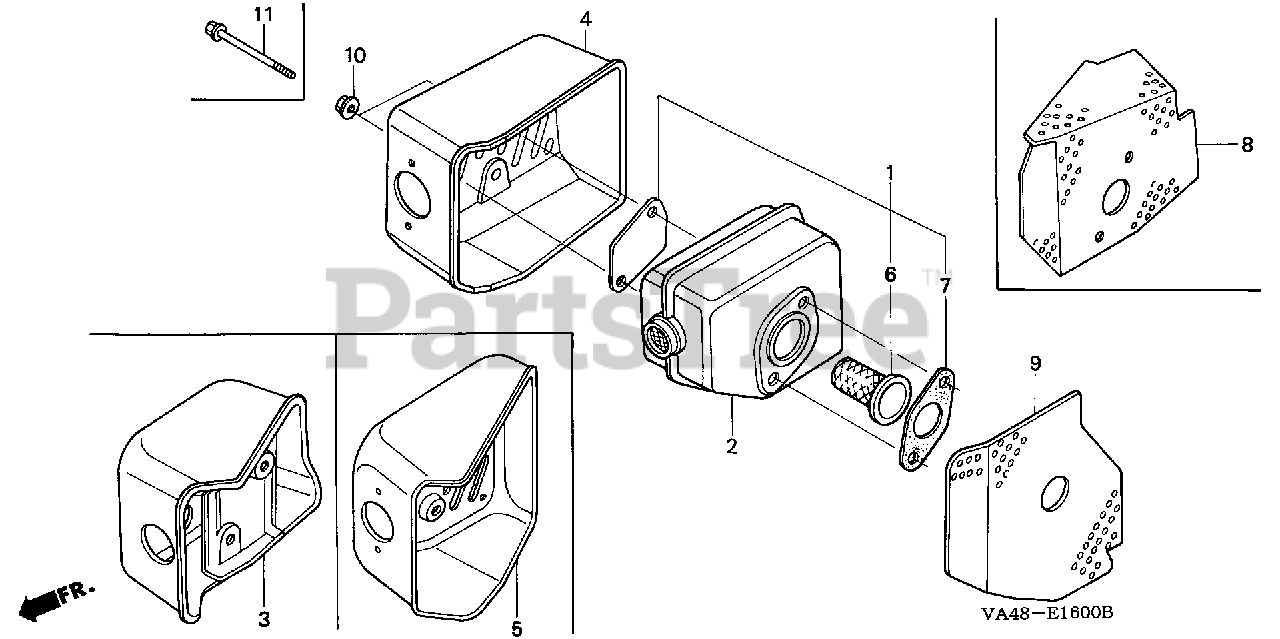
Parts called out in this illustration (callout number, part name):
1	ARRESTER KIT, SPARK
2	MUFFLER
5	PROTECTOR, MUFFLER
6	ARRESTER KIT, SPARK
7	GASKET, MUFFLER
9	GASKET, MUFFLER
10	NUT, SELF-LOCK (6MM)
